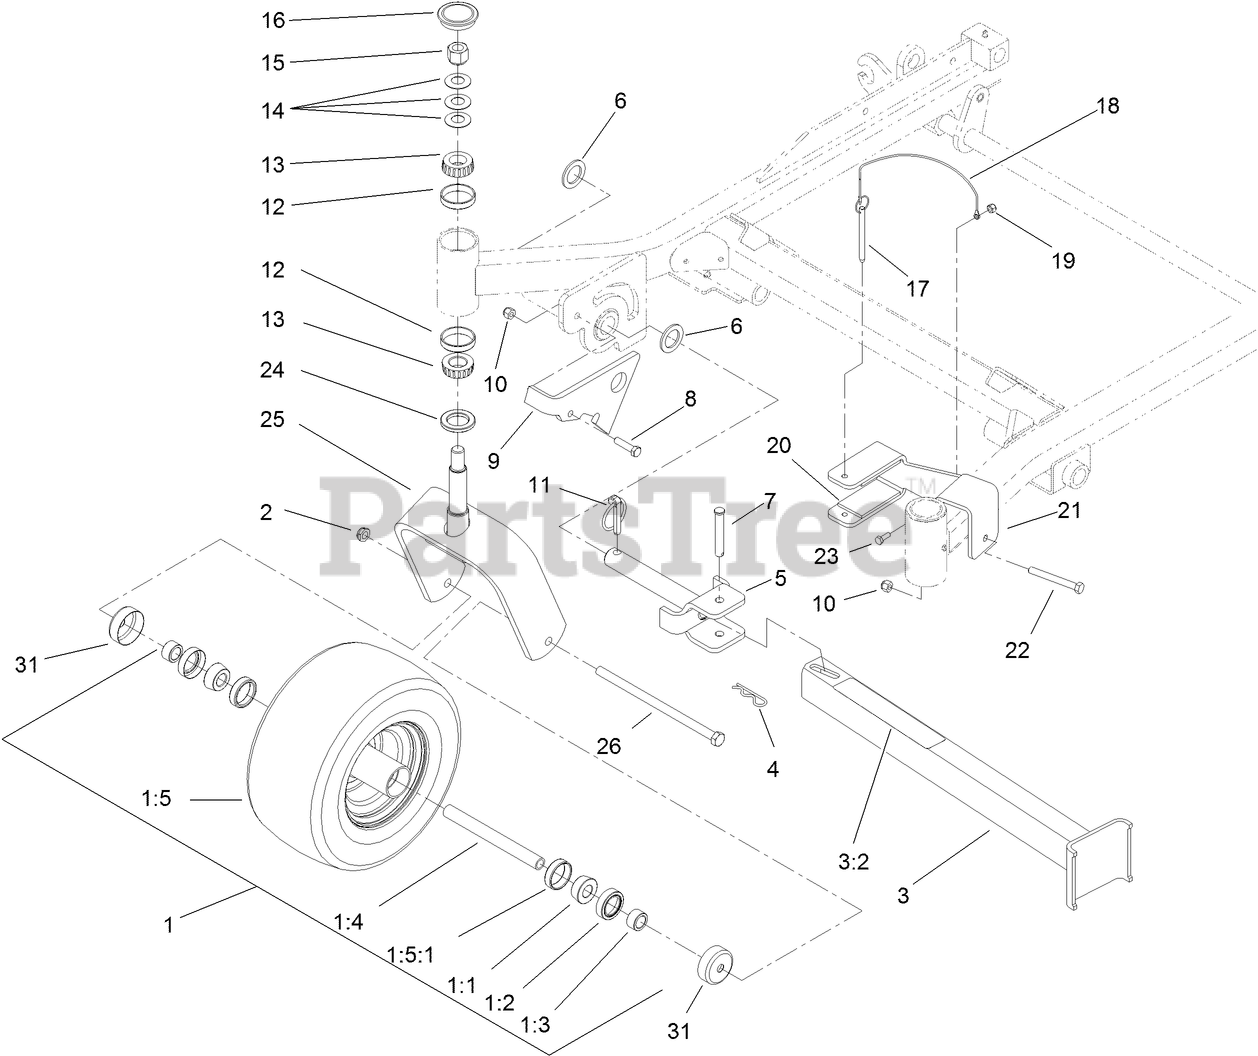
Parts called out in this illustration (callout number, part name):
1	WHEEL AND TIRE ASM
1:1	BEARING-CONE, TAPER
1:2	SEAL-CASTER
1:3	SPACER-NUT
1:4	AXLE-CASTER
1:5	WHEEL AND TIRE ASM
1:5:1	BEARING-CUP
2	NUT-LOCK, NI
3	Leg ASM
3:2	DECAL-Z STAND
4	PIN-HAIR
5	PIN-PIVOT
6	WASHER-THRUST
7	PIN-CLEVIS
8	SCREW-HH
9	BRACKET-LATCH
10	NUT-LOCK, NI
11	PIN-LYNCH
12	BEARING-CUP, TAPERED
13	BEARING-CONE, TAPERED
14	WASHER-BELLVILLE
15	NUT-LOCK, NI
16	CAP-GREASE
17	PIN-HITCH, COTTERLESS
18	LANYARD-NYLON
19	NUT-LOCK, NI
20	Cushion-Rubber
21	BRACKET-CRADLE
22	SCREW-HH
23	SCREW-HH
24	SEAL-GREASE
25	CASTER-FORK
26	Screw-HH
31	GUARD-SEAL
